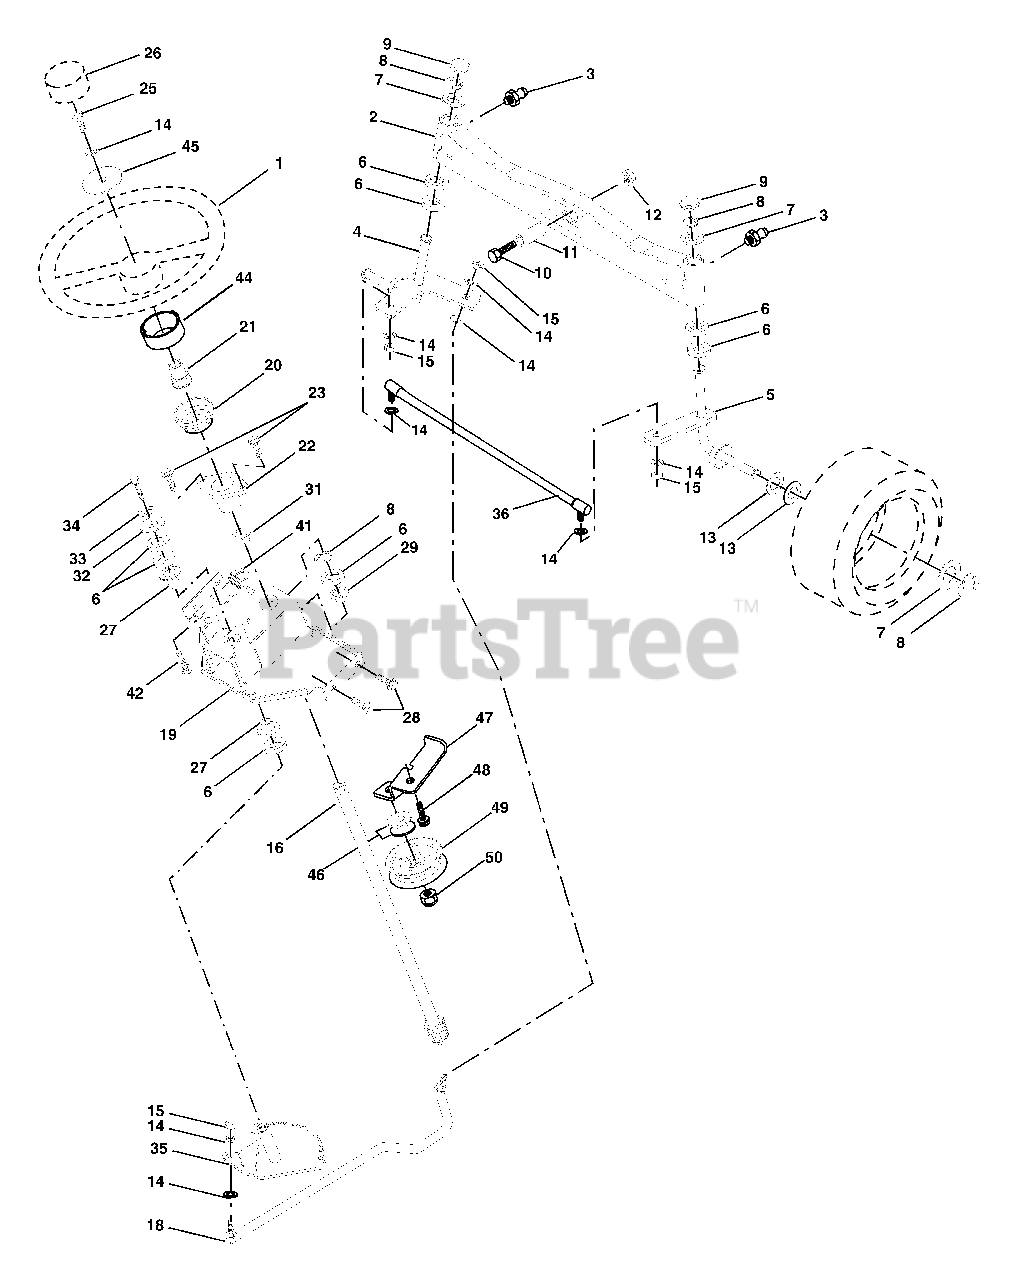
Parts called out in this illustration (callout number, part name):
1	Wheel, Steering
2	Axle Asm., Front
3	Fitting, Grease
4	Spindle Asm, LH
5	Spindle Asm., RH
6	Bearing, Race Thrust Harden
7	Washer 25/32 x 1-5/8 x 16 Ga.
8	Ring, Klip #T5304-75
9	Cap, Spindle
10	Bolt, Fin Hex 5/8-11 x 2-3/4
11	Spacer Brg Axle Front 1.570
12	Nut, Lock Flange 5/8-11 Unc
13	Washer 25/32 x 1-1/4 x 16 Ga.
14	Washer, Lock Hvy Hlcl Spr 3/8
15	Nut Lock Center 3/8-24 Unf
16	Shaft Asm., Steering
18	Draglink, Ball Joint Solid Vgt
19	Support Asm., Steering Vgt
20	Boot Steering
21	Adapter, Wheel Steering
22	Bushing, Strg.
25	Bolt, Fin Hex 3/8-16 x 1 Gr. 5
26	Cap , Wheel Steering
27	Bearing, Col. Strg.
28	Screw 3/8-16 x 3/4
29	Bearing, Flange
31	Bushing, Nyliner Snap
32	Washer 11/32 x 1 x 10 Ga.
33	Washer, Lock Hvy Hlcl Spr 5/16
34	Bolt, Hex Hd 5/16-18 x 3/4
35	Gear, Sector Steering
41	Bracket Switch Inerlock VGT97
42	Screw 5/16-18 x 1/2
44	Extension Steering Premium
45	Washer 13/32 x 1-1/20 x 11 Ga.
46	Washer Flat 13/32 x 1 x 10 Ga.
47	Bracket Asm. Idler
48	Screw 3/8-16 x .75
49	Pulley Idler Flat
50	Nut Lock Flg 3/8-16 Unc
